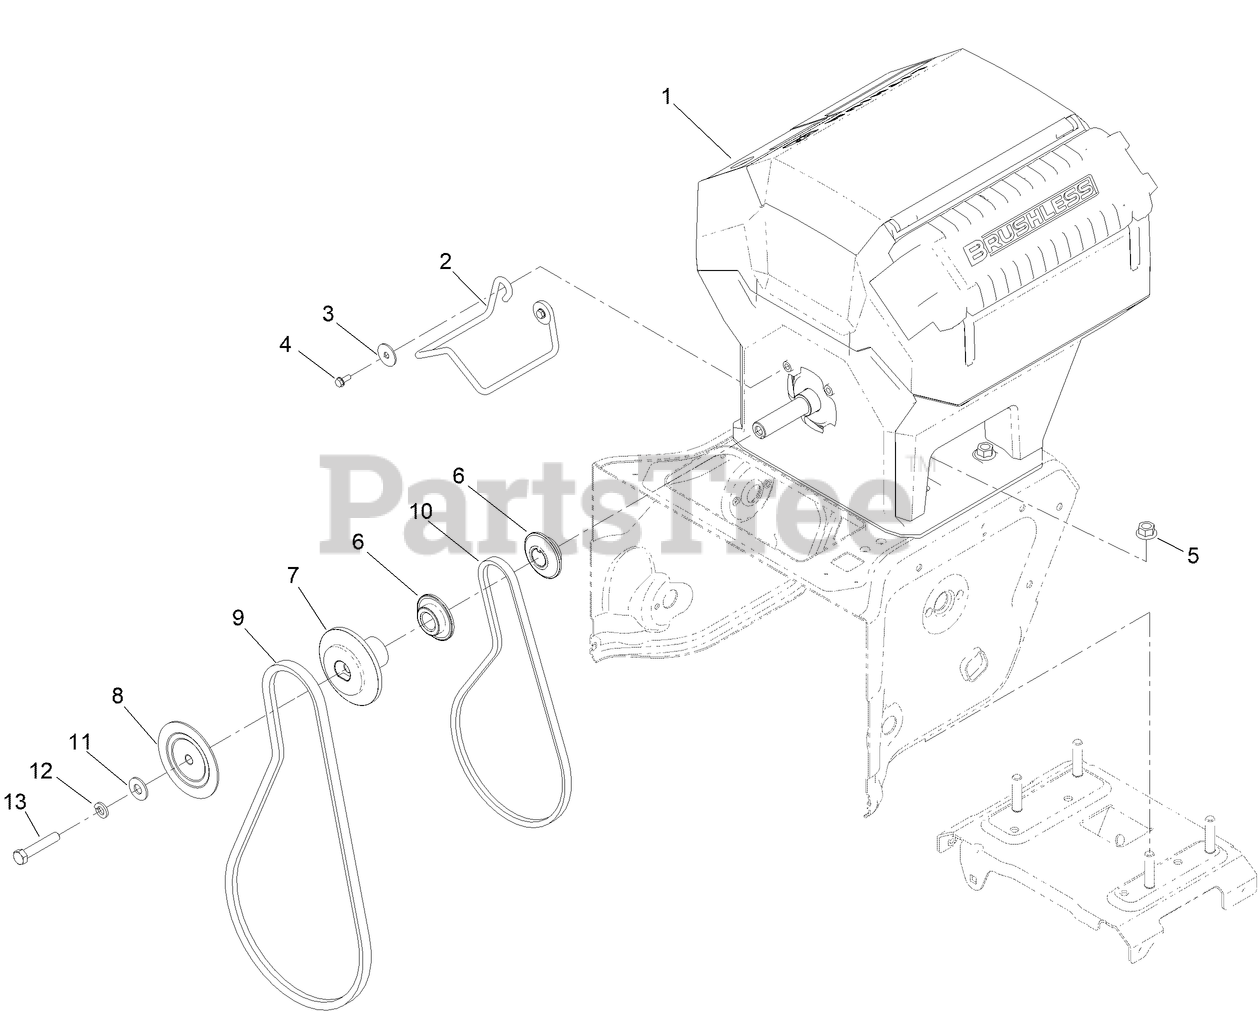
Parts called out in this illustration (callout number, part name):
1	POWERHEAD-60V
2	GUIDE-BELT
3	WASHER-FLAT
4	SCREW-HWH, THD ROLL
5	NUT-LOCK
6	PULLEY-ENGINE, TRACTION
7	PULLEY-AUGER, REAR
8	PULLEY-AUGER, FRONT
9	BELT-V
10	BELT-V
11	WASHER-FLAT
12	WASHER-LOCK
13	SCREW-HH
